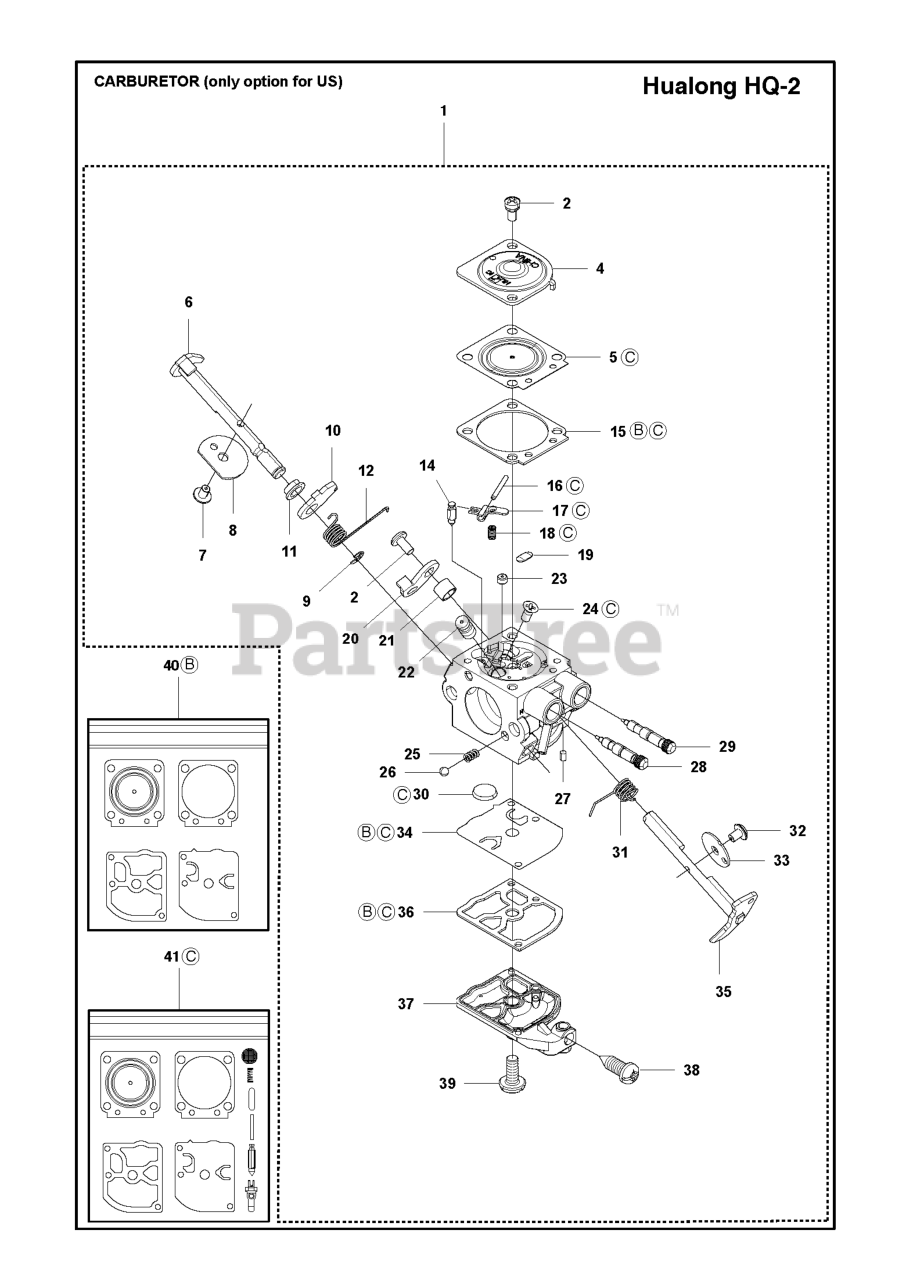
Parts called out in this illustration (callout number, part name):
1	CARBURETOR
40	KIT GASKET
41	REPAIR KIT
